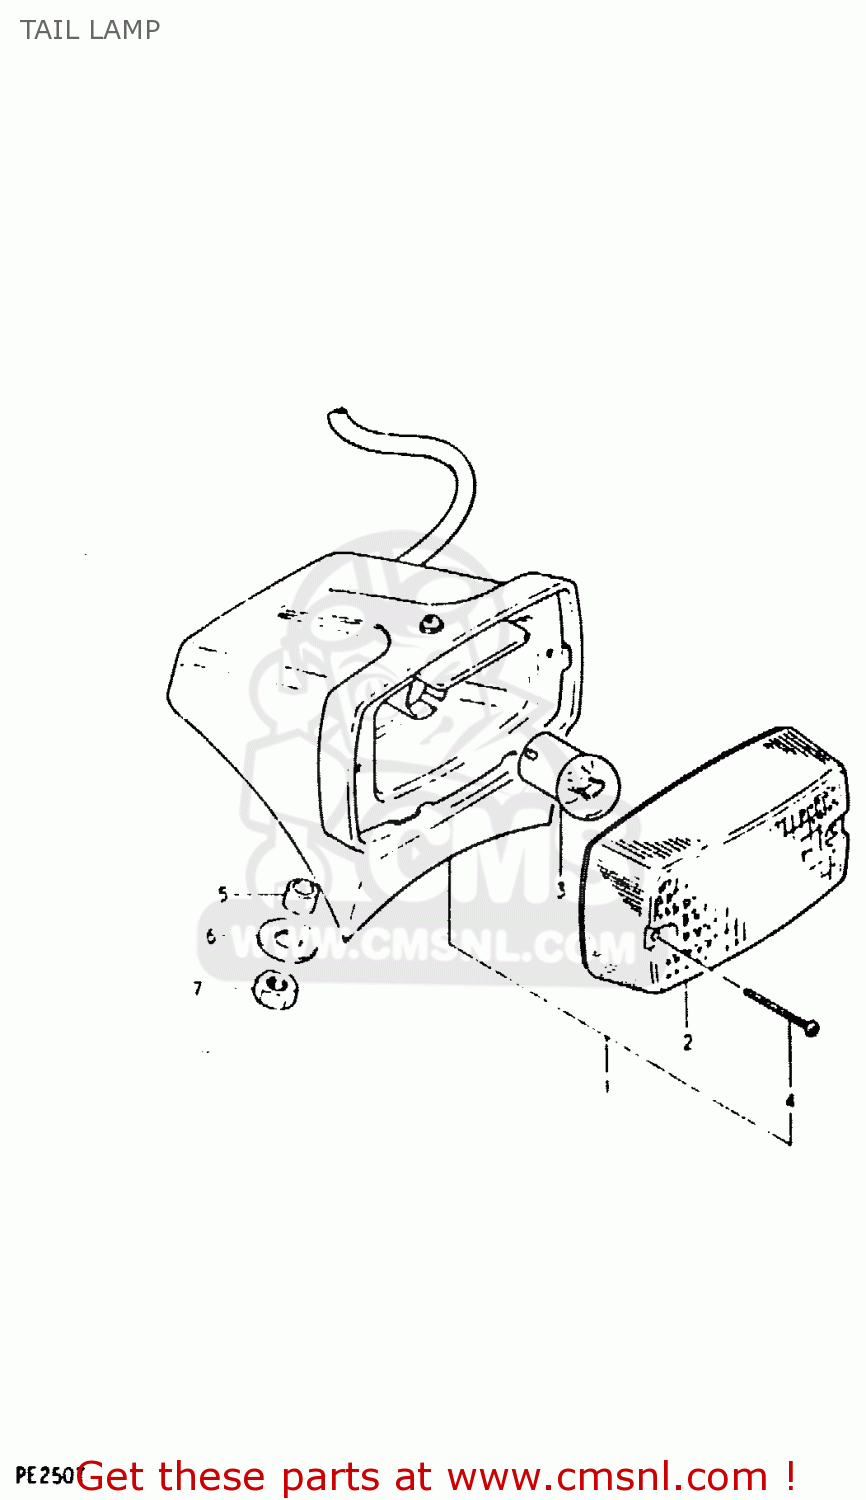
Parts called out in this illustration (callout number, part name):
1	LAMP ASSEMBLY,REAR COMBINATION
2	LENS
3	BULB(6V5W,TOKAI DENSO)
4	SCREW,REAR COMBINATION LAMP LENS
5	SPACER (6.1X9X9)
6	WASHER
7	NUT
